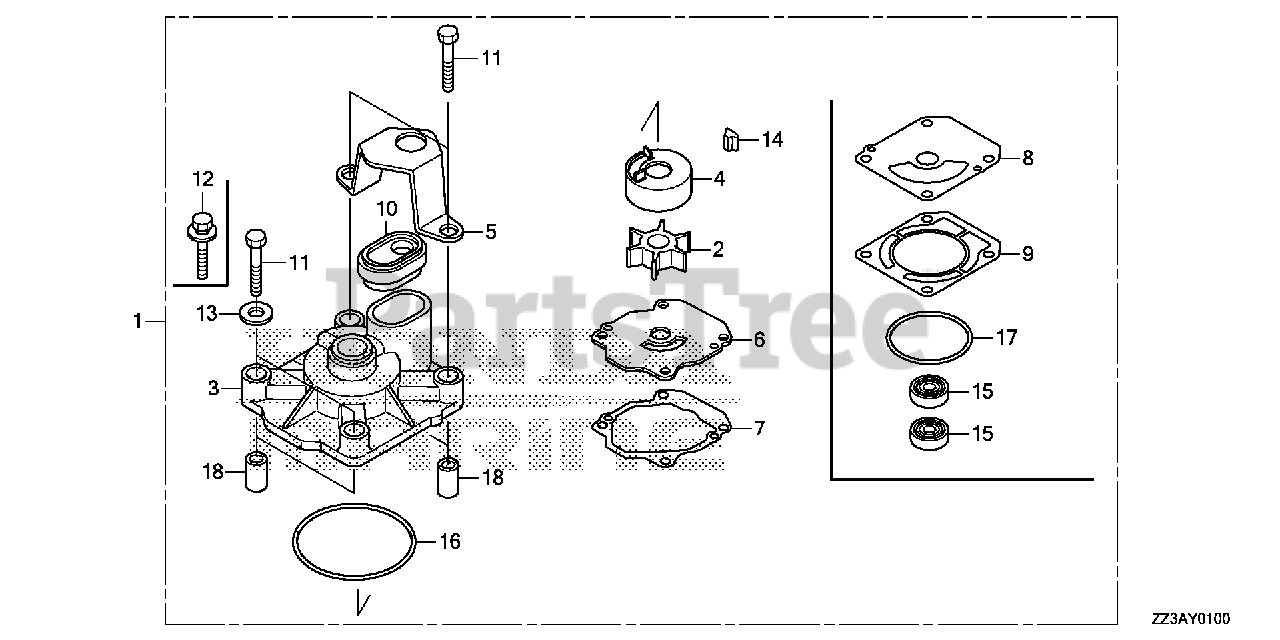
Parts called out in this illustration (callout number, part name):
1	PUMP KIT, IMPELLER
2	IMPELLER, PUMP
3	HOUSING, IMPELLER
4	LINER, PUMP
5	HOLDER, WATER TUBE SEAL
6	COVER, IMPELLER
7	GASKET, IMPELLER
10	RUBBER, WATER TUBE SEAL
11	BOLT, HEX. (8X40)
12	BOLT-WASHER (8X40)
14	KEY, WOODRUFF
16	O-RING, WATER PUMP
18	COLLAR, DISTANCE
